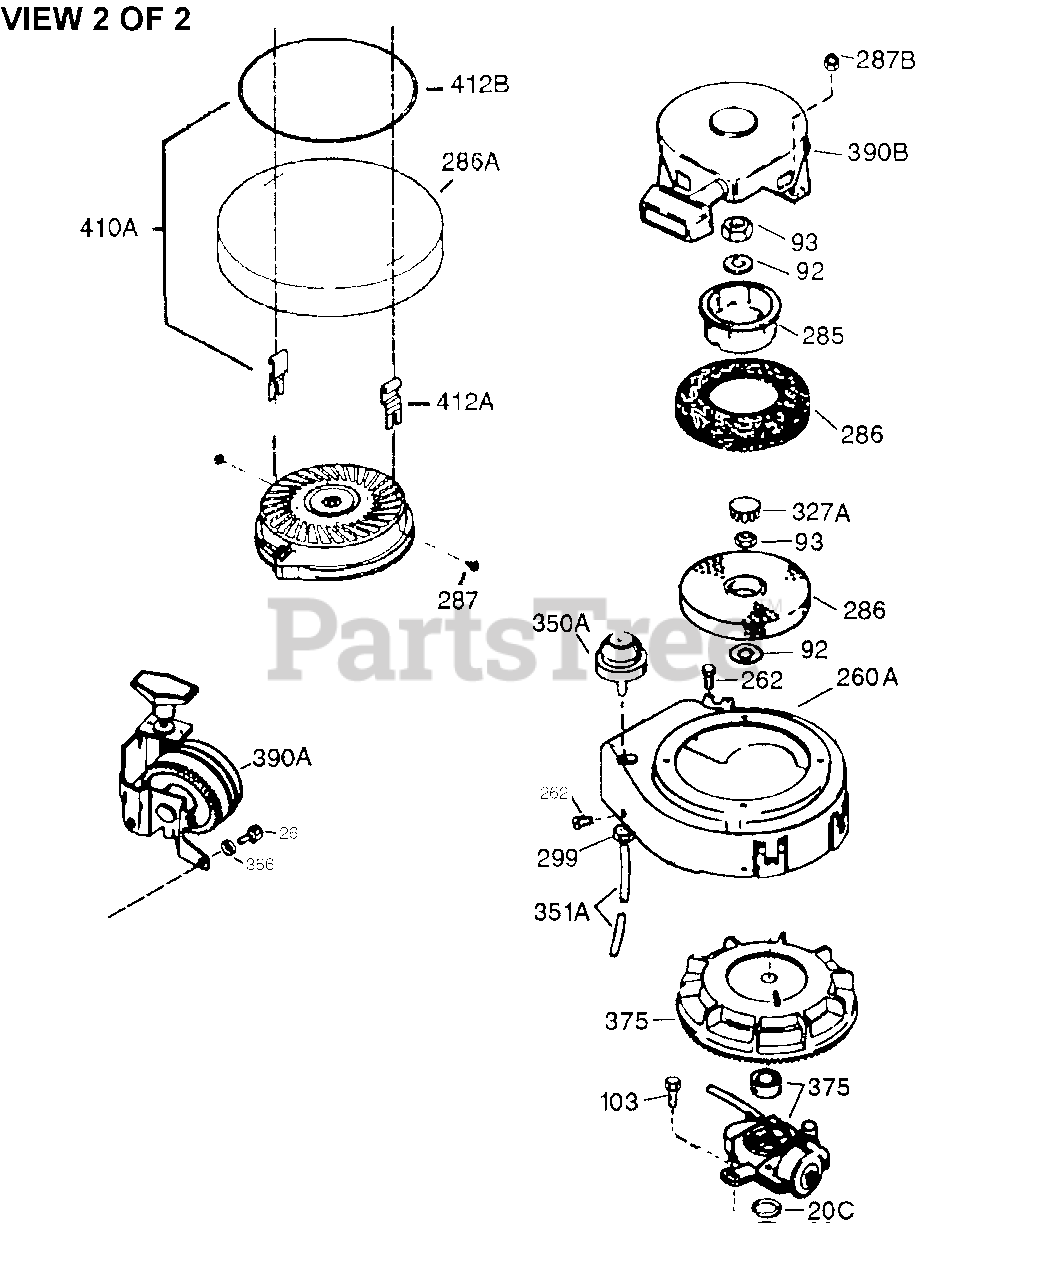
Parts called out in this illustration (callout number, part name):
20A	Oil Seal
20B	Oil Seal Retainer
20C	Oil Seal Retainer Spring
28	Oil Seal
28A	Oil Seal Retainer
28B	Oil Seal Retainer Ring
38	Retainer Ring Used in early producti on
92	Belleville Washer
93	Flywheel Nut
103A	Screw, 1/4-20 x 3/4"
178	Nut & Lock Washer 1/4-28
260A	Blower Housing NOTE: On some late pr oduction models, the top mounted rewi nd starter is riveted to the blower h ousing. If either the starter or blo wer housing needs replacement, the ot her may need the holes used for pop r iveting enlarged to ac
262	Screw, 1/4-20 x 7/16"
285	Starter Cup
286	Starter Screen
299	Lock Nut, 1/4-20
350A	Primer Assy.
351A	Primer Line
365A	Screw, 8-32 x 1/4"
375	Magneto NOTE: The complete magneto i s not available as an assembly. The magneto number is shown for reference purposes only. Order component part s individually, as shown in parts lis t. (Refer to Division 5, Section B, p age 35 or Fiche 23B, Gri
390B	Rewind Starter NOTE: On some late pr oduction models, the top mounted rewi nd starter is riveted to the blower h ousing. If the starter or blower hou sing needs replacement, the other may need the holes used for pop riveting enlarged to accomodate
